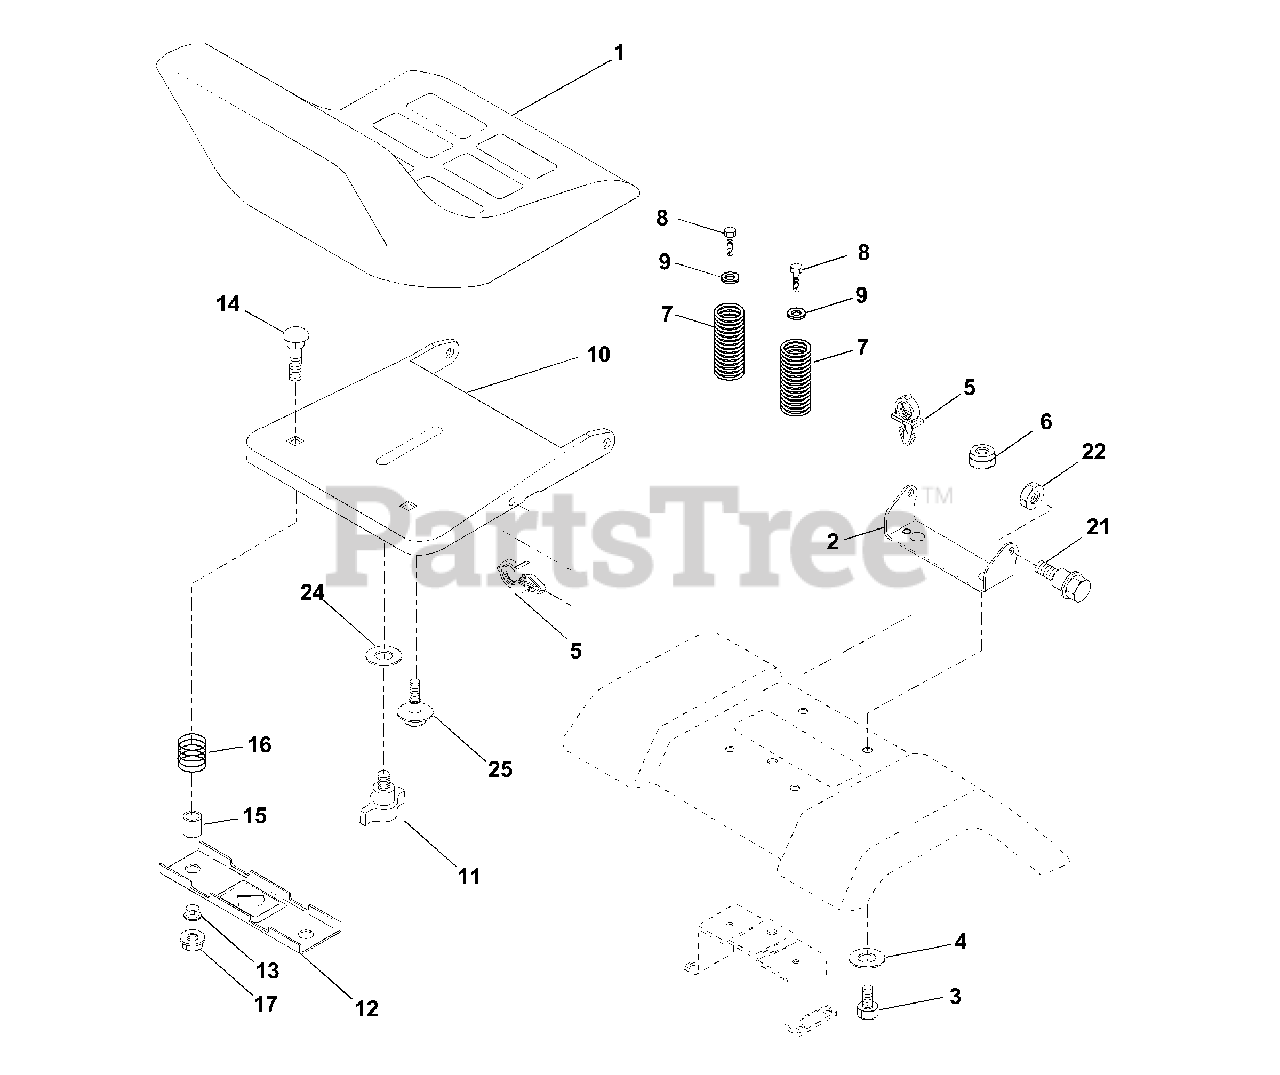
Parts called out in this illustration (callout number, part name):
1	Seat
2	Bracket Pivot Seat 8 720
3	Bolt Fin Hex 3/8-16 Unc X 1
4	Washer 13/32 X 1 X 10 Ga
5	Clip Push-In
6	Nut Hex w/Ins. 3/8-16 Unc
7	Spring Seat Cprsn 2 250 Blk Zi
8	Screw 3/8-16 X 1.5
9	Washer 13/32 X 1 X 14 Ga.
10	Pan Seat
11	Knob Seat
12	Bracket Mounting Switch
13	Bushing Snap Blk Nyl 50 Id
14	Bolt Rdhd Sqnk 1/4-20x1-1/2
15	Spacer Split 28x 88
16	Spring Cprsn
17	Nut Lock 1/4 Lge Flg Gr 5 Zinc
21	Bolt Shoulder 5/16-18 Unc
22	Nut Hex Lock W/Ins 5/16-18
24	Washer 17/32 X 1-3/16 X 12 Ga.
25	Bolt Shoulder 5/16-18 X 62
